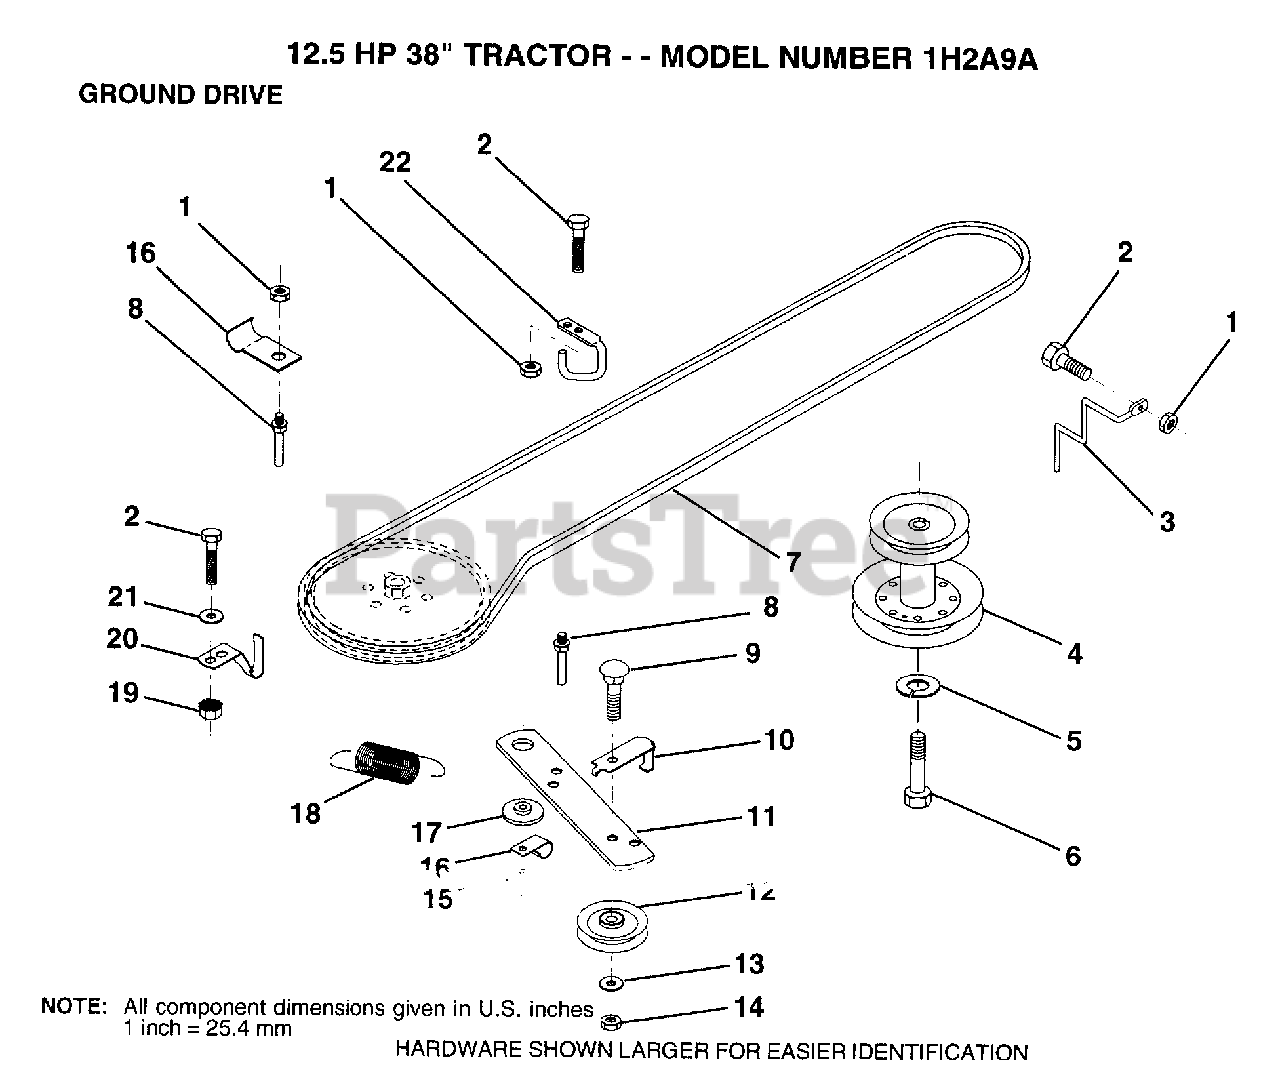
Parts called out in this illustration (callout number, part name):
2	BOLT
3	KEEPER MWR DR BLT
5	LOCKWASHER
6	BOLT
7	V BELT
8	"KEEPER,DRIVE BELT"
9	BOLT
10	"KEEP,IDLER DR BEL"
12	PULLEY.IDLER.FLAT
13	WASHER
14	LOCKNUT
16	"CLIP,INSULATOR"
17	SPACER RETAINER
20	"KEEPER,DR BELT "
21	WASHER
22	"KEEPER,FRA DR BEL"
